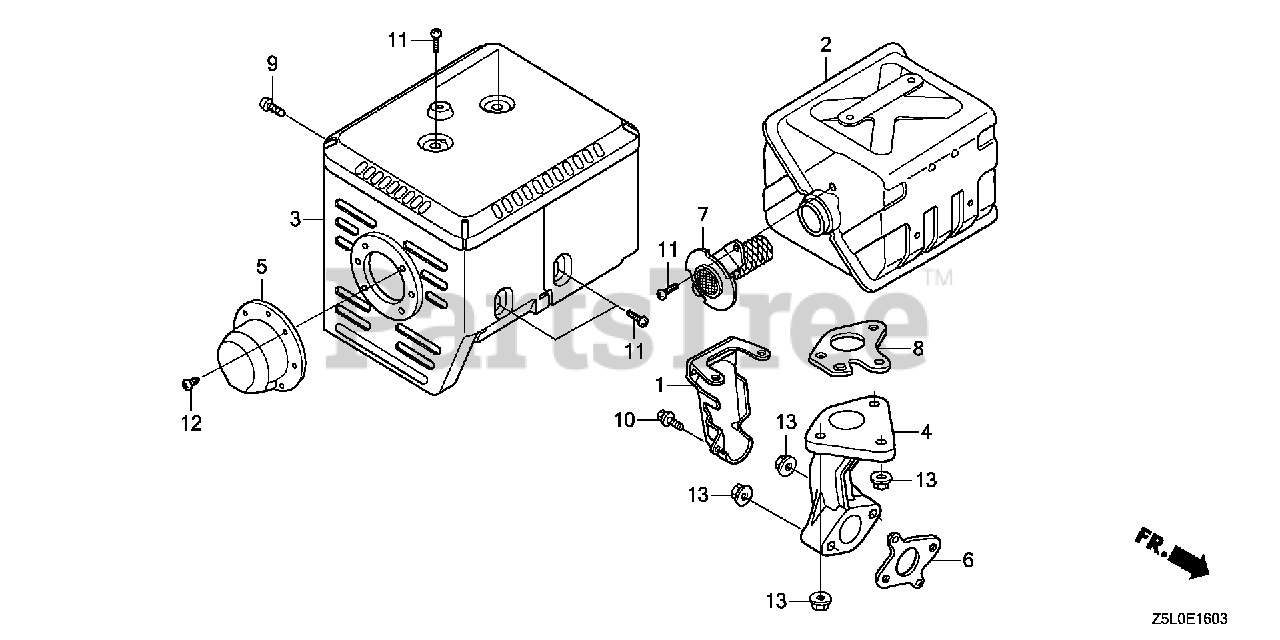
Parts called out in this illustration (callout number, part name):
2	MUFFLER
3	PROTECTOR, MUFFLER
6	GASKET, EX. PIPE
7	ARRESTER, SPARK
8	GASKET, MUFFLER (ARRESTER) (NIPPON LEAKLESS)
9	SCREW, TAPPING (6X10)
11	SCREW, TAPPING (5X8)
13	NUT, FLANGE (8MM)
